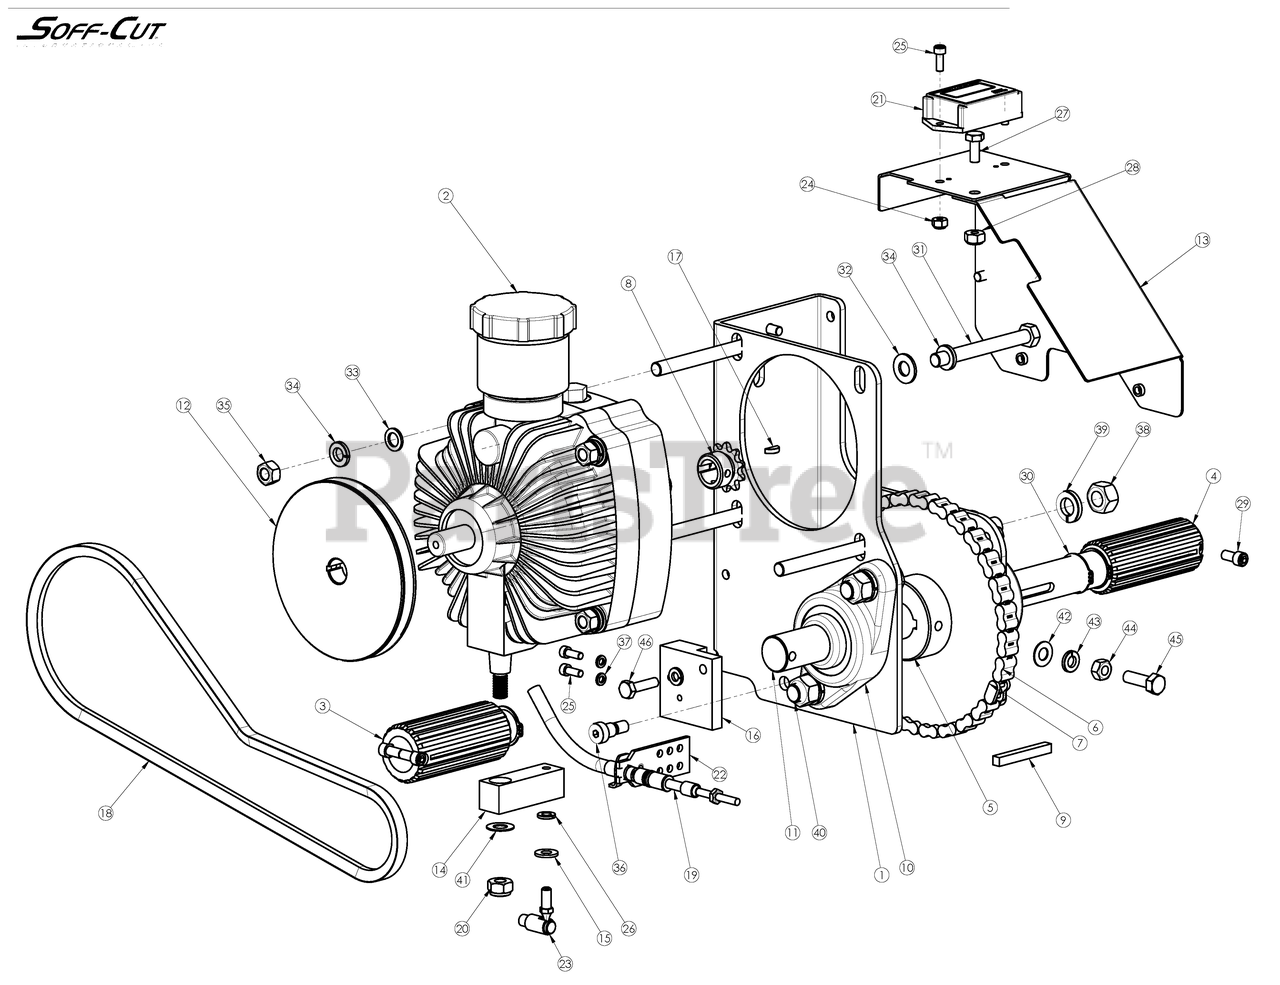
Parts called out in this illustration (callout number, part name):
2	HYDROSTATIC PEDAL ASSY
28	NYLOC NUT 1/4-20 CAD PL.
31	HEX BOLT 3/8-16-3 1/2 CAD GR 5
32	FLAT WASH 3/8 STL CAD
45	HEX BOLT 5/16-18-1 CAD GR 5
